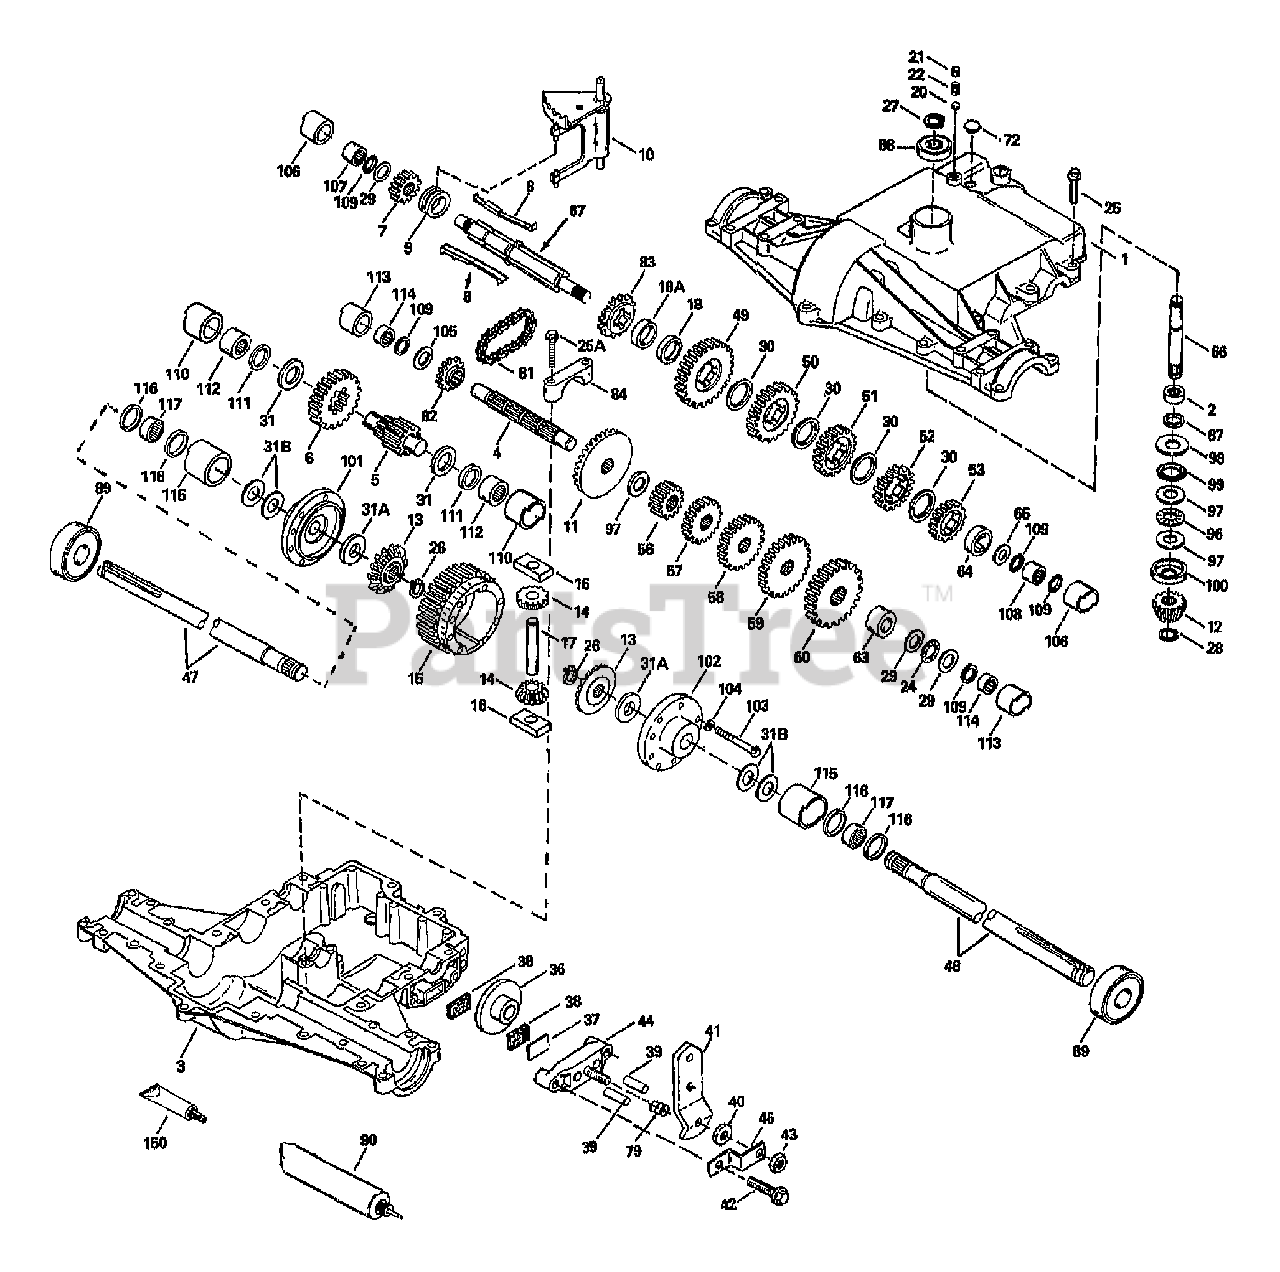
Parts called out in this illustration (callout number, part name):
2	NEEDLE BEARING
4	COUNTERSHAFT
5	OUTPUT SHAFT
6	OUTPUT GEAR
7	SPUR GEAR
8	SHIFT KEY
10	ROD & FORK
11	BEVEL GEAR
12	INPUT PINION
13	BEVEL GEAR
14	BEVEL GEAR
15	RING GEAR
16	DRIVE BLOCK
17	DRIVE PIN
22	SPRING
24	THRUST BEARING
26	RET RING
27	RET RING
28	RET RING
29	WASHER
30	WASHER
36	BRAKE DISK
37	BRAKE PAD PLATE
38	BRAKE PAD
39	DOWEL PIN
41	BRAKE LEVER
49	SPUR GEAR
50	SPUR GEAR
51	SPUR GEAR
52	SPUR GEAR
53	SPUR GEAR
56	SPUR GEAR
57	SPUR GEAR
58	SPUR GEAR
59	SPUR GEAR
60	SPUR GEAR
66	INPUT SHAFT
67	BRAKE SHAFT
81	ROLLER CHAIN
82	SPROCKET
83	SPROCKET
84	BEARING CAP
87	OIL SEAL
88	BALL BEARING
89	BALL BEARING
96	THRUST BEARING
107	NEEDLE BEARING
108	NEEDLE BEARING
109	O RING
111	SQUARE-CUT RING
112	NEEDLE BEARING
114	NEEDLE BEARING
116	SQUARE-CUT RING
117	NEEDLE BEARING
150	GASKET ELIMINATOR
